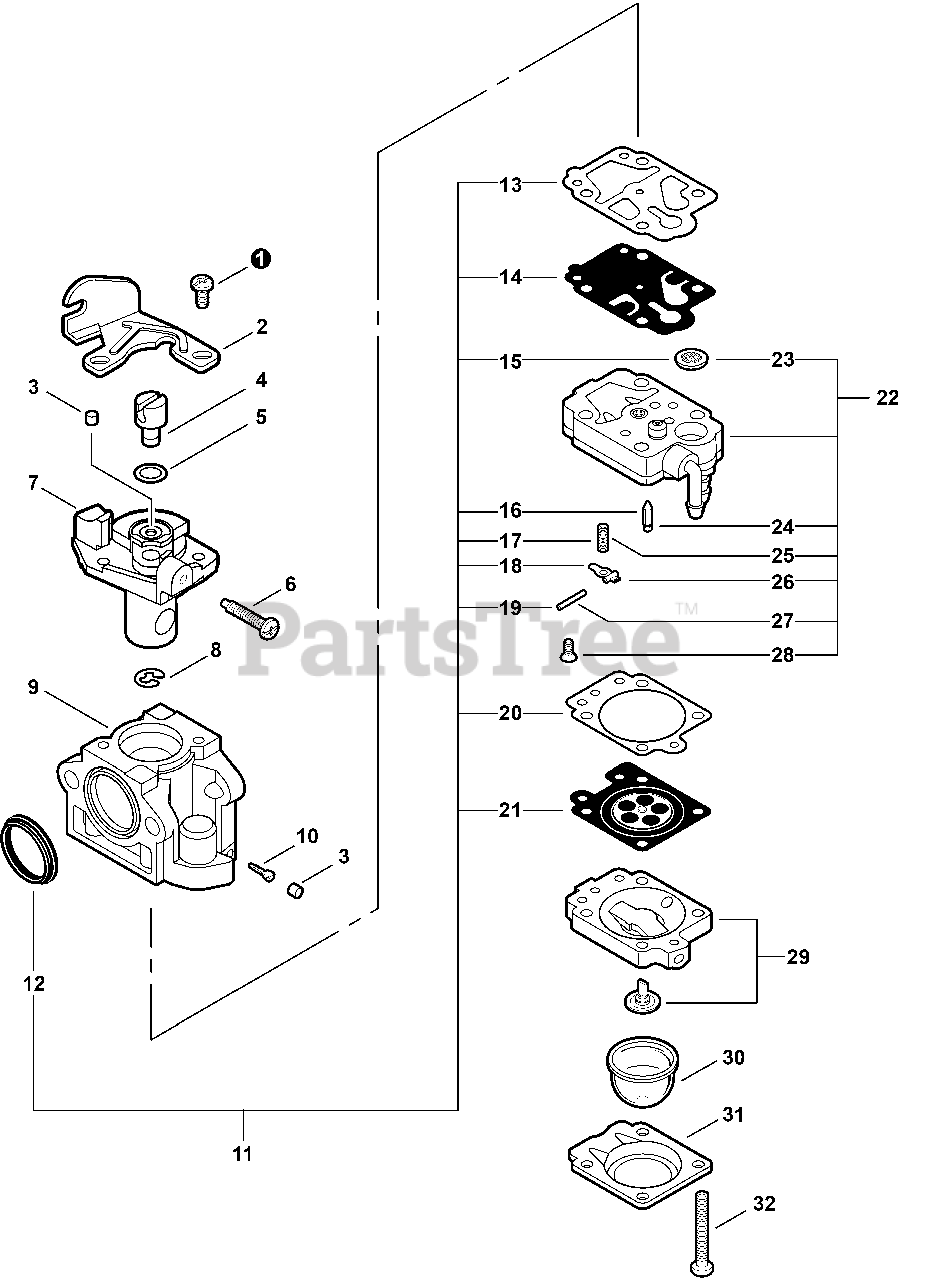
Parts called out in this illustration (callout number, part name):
2	BRACKET, CABLE
3	CAP, LIMITER
6	SCREW, IDLE ADJUST
7	THROTTLE VALVE ASY
8	RING, RETAINING
9	BODY, CARBURETOR
10	NEEDLE - HIGH SPEED
11	REPAIR KIT
12	RING, PACKING
13	GASKET, PUMP
14	DIAPHRAGM, PUMP
15	STRAINER
16	VALVE, INLET NEEDLE
17	SPRING, METERING LEVER
18	LEVER, METERING
19	PIN, METERING LEVER
20	GASKET, DIAPHRAGM
21	DIAPHRAGM, METERING
22	PUMP BODY ASY
23	STRAINER
24	VALVE, INLET NEEDLE
25	SPRING, METERING LEVER
26	LEVER, METERING
27	PIN, METERING LEVER
28	SCREW, METERING LEVER PIN
29	PURGE BASE ASY
30	BULB, PURGE
31	RETAINER, PURGE BULB
32	SCREW, PUMP COVER
